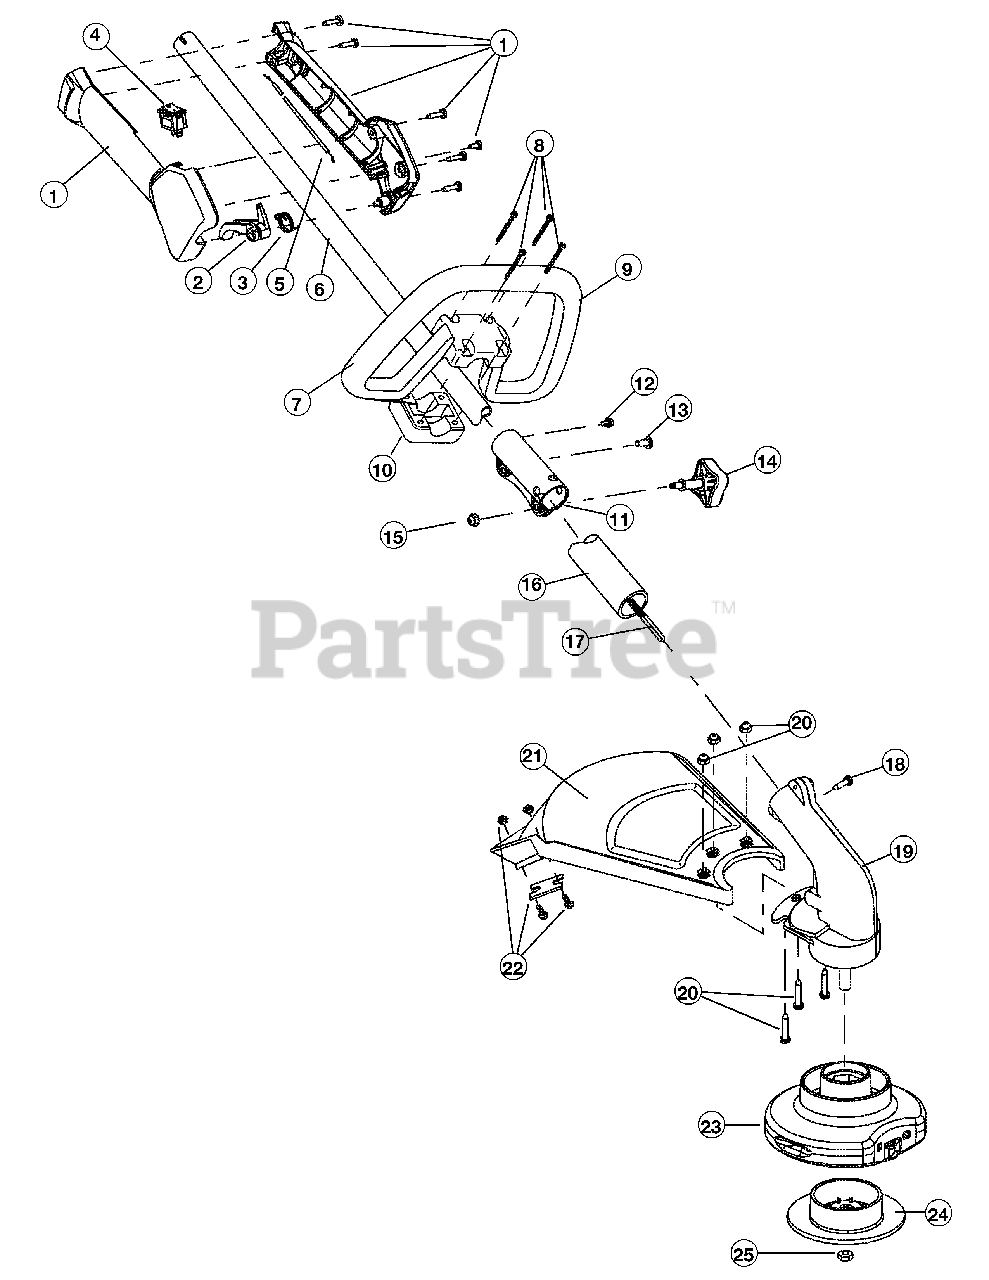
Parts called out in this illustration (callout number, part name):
1	Throttle Housing Assembly (includes 2-4)
2	Throttle Trigger
3	Throttle Trigger Spring
5	Throttle Cable Assembly
6	Upper Drive Shaft Housing Assembly
7	Deluxe D-Handle Assembly (includes 8-10)
9	Deluxe D-Handle
10	Bottom Clamp
11	Split Boom Coupler (includes 12-15)
14	Adjustment Knob
15	Knob Retaining Nut
16	Lower Drive Shaft Housing Assembly
17	Lower Flexible Drive Shaft
18	Anti-Rotation Screw
19	Gear Box Assembly
20	Shield Mounting Hardware
21	Shield Assembly (includes 22)
22	Blade Assembly
23	Fixed Head Assembly (includes 24 & 25)
24	Glide Cap
25	Locknut
